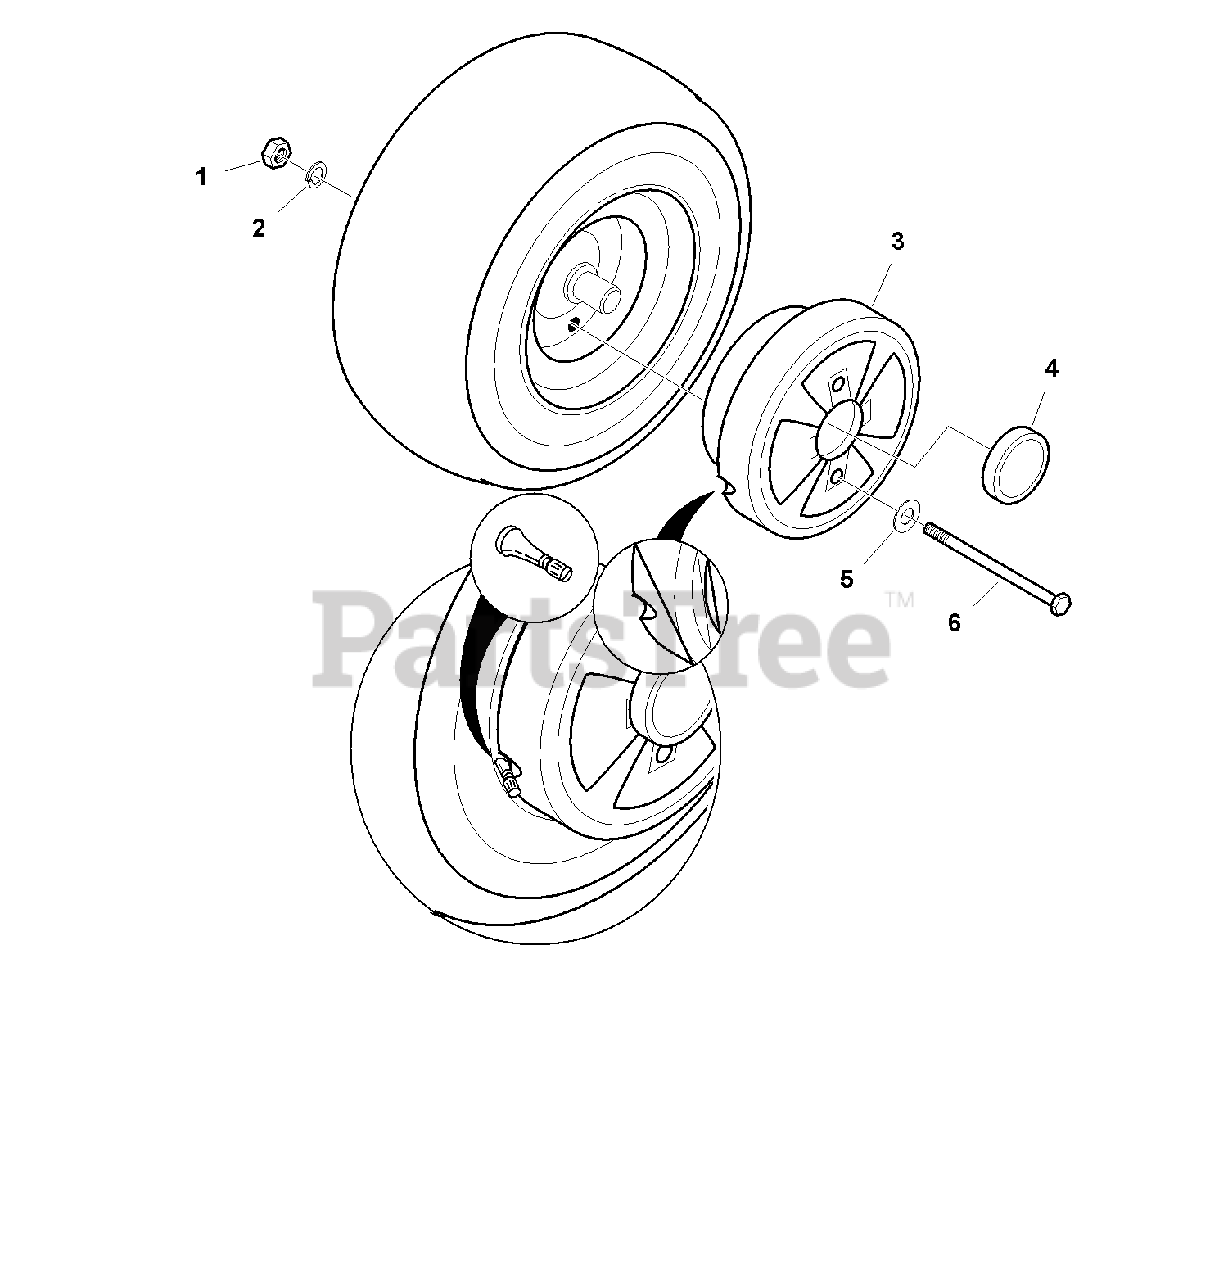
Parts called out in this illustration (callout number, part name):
1	NUT, Hex, 3/8-16
2	LOCKWASHER, 3/8
3	WEIGHT, Wheel (Includes Ref. Nos. 1, 2, 4, 5 & 6)
4	CAP, Wheel Weight
5	WASHER, 3/8
6	CAPSCREW, Hex, 3/8-16 x 8
